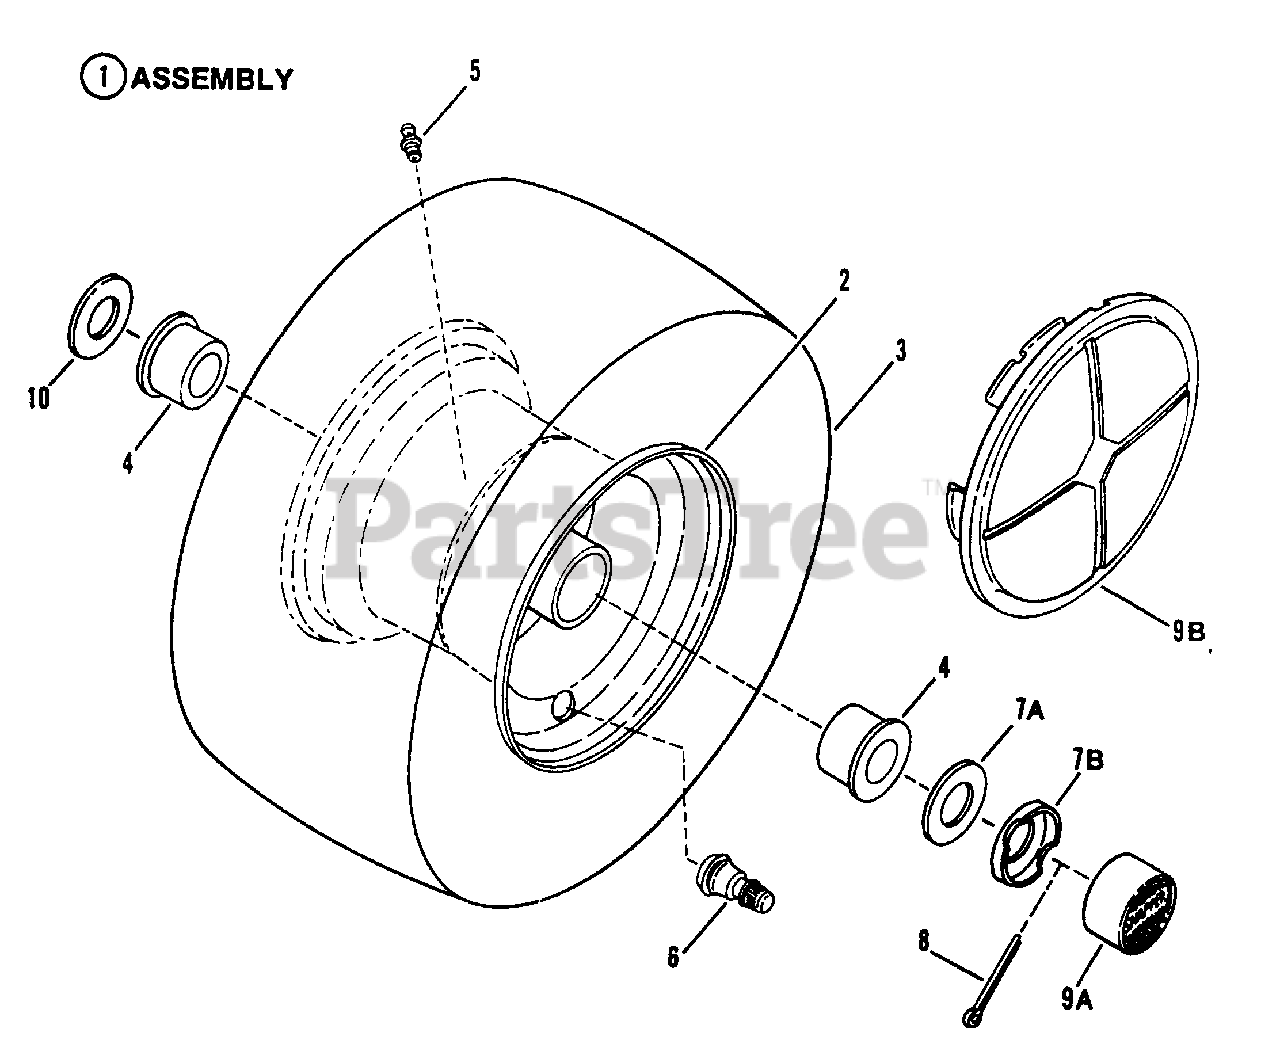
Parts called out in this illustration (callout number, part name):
1	ASSEMBLY, Front Tire & Rim
2	RIM, 5.50 x 4.00
3	TIRE, 13 x 5.00
3	TIRE, 15 x 6.00
4	BEARING, Wheel
5	FITTING, Lube 1/4-28 Tapered Thread
6	VALVE, Air (Snap-in)
7A	WASHER, 49/64 I.D. x 1-1/2" O.D.
7B	RETAINER, Hub-Cap (30" Model)
8	COTTER-PIN
9A	HUB-CAP
9B	WHEEL-COVER
10	WASHER, 25/32 I.d. x 1-1/2" O.D.
